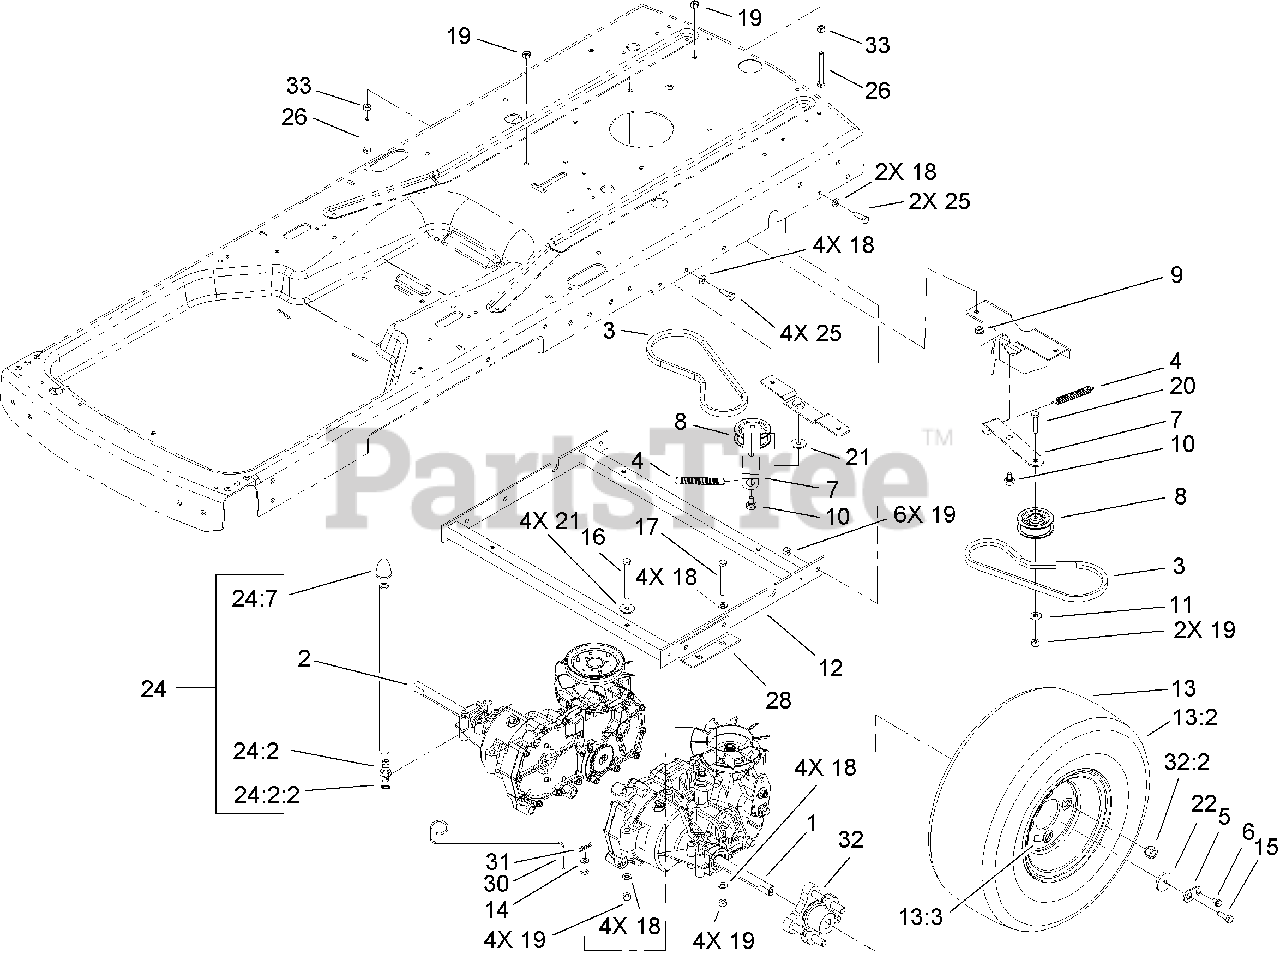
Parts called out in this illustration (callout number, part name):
1	TRANSAXLE-HYDRO, LH
2	TRANSAXLE-HYDRO, RH
5	TAB-LOCKING
6	SCREW-HHF
7	ARM-IDLER
8	PULLEY-IDLER
10	BOLT-SHOULDER
11	WASHER-FLAT
12	HYDRO MOUNT ASM
13	WHEEL AND TIRE ASM
13:3	STEM-VALVE
14	WASHER-FLAT
15	SCREW-HH
16	SCREW-HH
17	SCREW-HH
18	WASHER-FLAT
19	NUT-LOCK, NI
20	SCREW-HH
21	WASHER-PIVOT
22	WASHER-WHEEL
24	VENT HOSE ASM
24:2	FITTING ASM
24:7	CAP VENT ASM
25	SCREW-HH
26	SCREW-HH
28	SUPPORT-HYDRO
30	ROD-BYPASS
32:2	NUT-LUG
33	NUT-HEX
